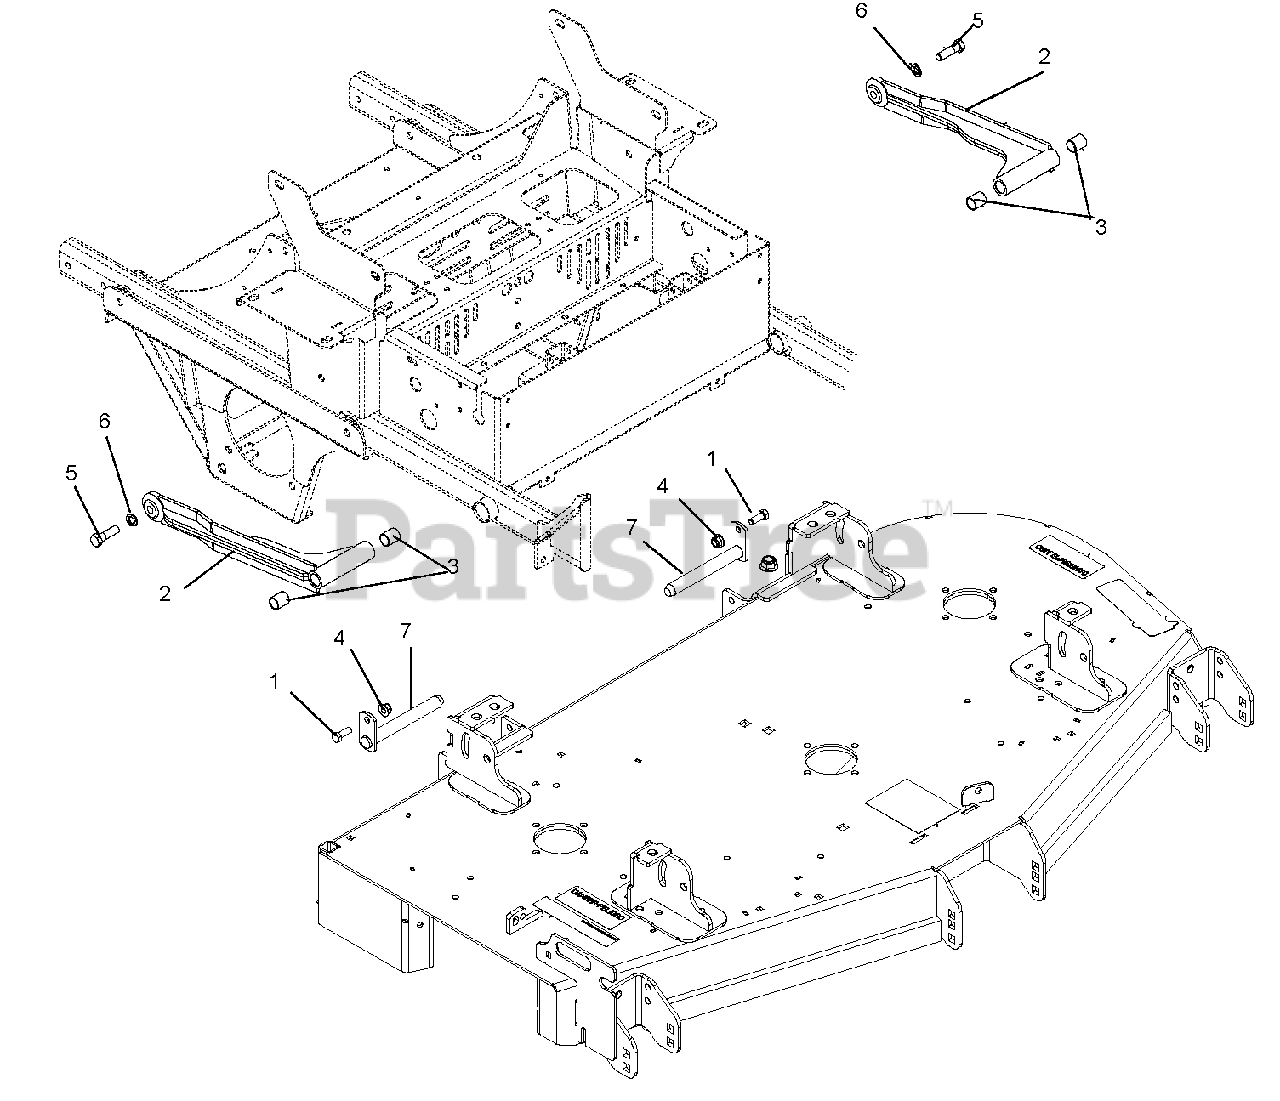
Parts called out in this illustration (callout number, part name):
1	Bolt, Hex .38-16 x 1.00 GR5 YWZC
2	Deck Stabilizer Arm - BLACK
3	Bearing, .75 x .875 x 1.00
4	Nut, Locking-Nylon-Flange .38-16
5	Bolt, Hex .50-13 x 1.75 GR5 EP80 YZ
6	Washer, Lock .50 x .125 REG YWZC
7	Weldment, Mower Mounting Pin
